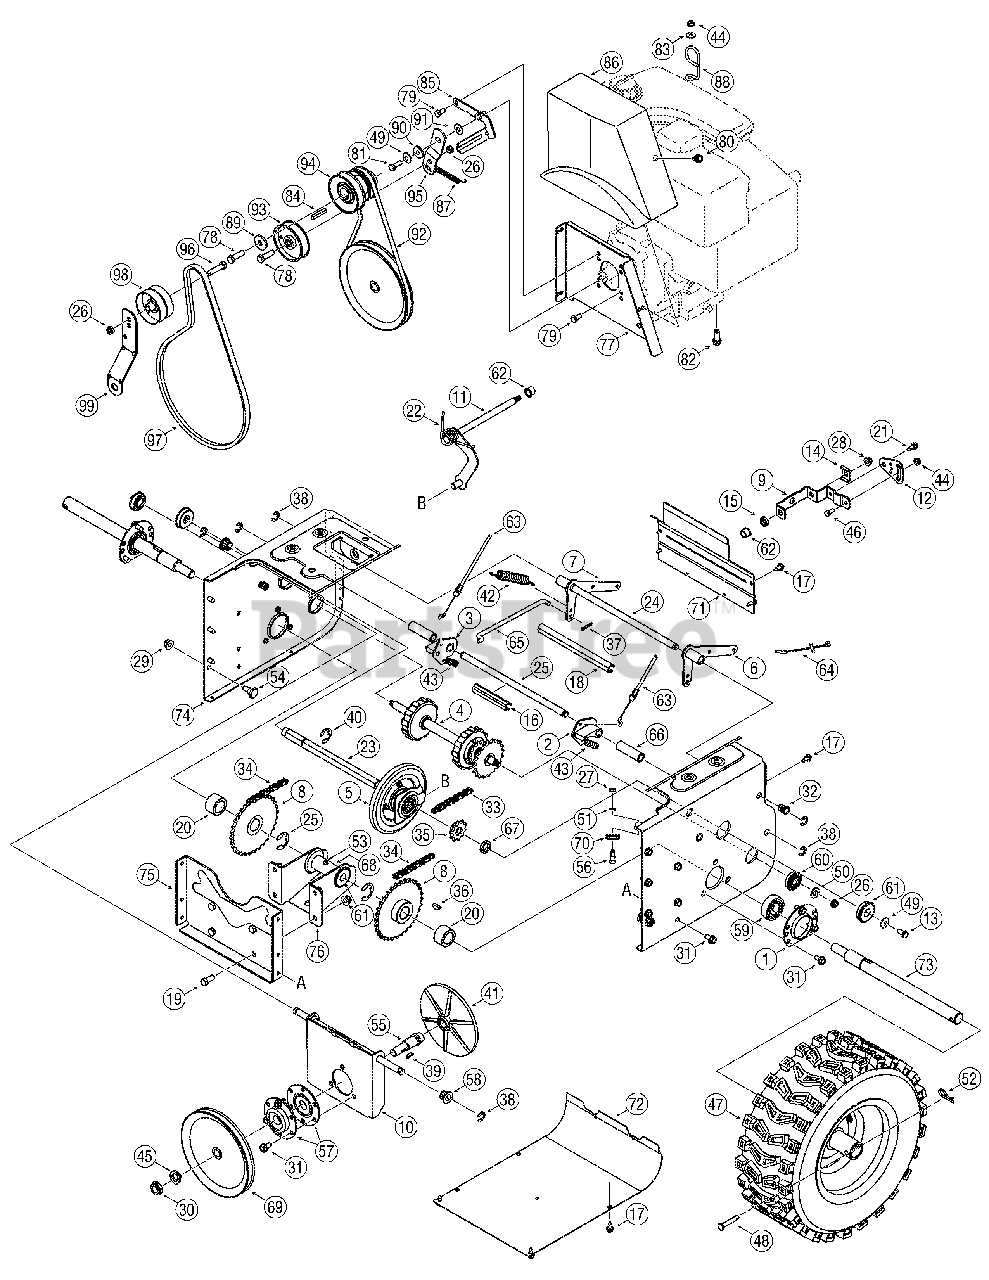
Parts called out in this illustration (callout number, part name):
1	Housing, Bearing
2	Dogg, Steering Drive, LH
3	Dogg, Steering Drive, RH
4	Shaft Assembly, Steering
5	Assembly, Friction Wheel
5	Wheel, Friction, Bonded
5	Screw, Hex Wash
11	Rod Assembly, Shift
13	Screw, Hex Cap Lock,
14	Bracket, Spacer, Shft.
15	Spacer, .515 ID x .750 OD
16	Spacer, .51 ID x 3.66 Lg.
17	Screw, Hex Wash.
18	Spacer, .51 ID x 7.895 Lg.
19	Screw, Hex Cap, 3/8-16
20	Spacer., 1.0 ID x 1.50 OD
21	Screw, Shoulder, .368 x .113
22	Spring, Torsion
23	Shaft, Hex Drive
24	Shaft, Actuator
25	Ring, Retainer
26	Nut, Hex Insert Jam Lock
27	Nut, Hex, 1/4-28 GR5
28	Nut, Hex Flnge Insert Lk
29	Nut, Hex Flnge Insert Lk
30	Nut, Hex Insert Jam Lk
31	TT Screw, 5/16-18 x .750
32	Nut, Insert 3/8-16
33	Chain, Endless, #41 x 36L
34	Chain, #420 x 40L
35	Sprocket, #41 x 10T
36	Key, Woodruff
37	Pin, Internal Cotter
38	E-Ring
39	Key, Hi-Pro, 3/16 x 5/8
40	Ring, Retaining
41	Plate, Drive
42	Spring, Extension
43	Spring, Extension
44	Flange, Lock Nut, 1/4-20
45	Washer, Lock, 5/8
46	Screw, 1/4-20 x .620
47	Wheel Assembly - LH
47	Valve
48	Pin, Clevis
49	Washer, Bell., .34 x .872 x .06
50	Washer, .406 x .875 x .059
51	Washer, Lock, 1/4
52	Pin, Internal Cotter
53	Fitting, Lube, 3/16 Drive
54	Screw, Shoulder, .498 x .34
55	Spindle, Drive Plate
56	Screw, Hex Shldr., 1/4-28
57	Assembly, Bearing/Housing
58	Bearing, Hex Flange
59	Bearing, Self Aligning
60	Bearing, Ball
61	Bearing, Ball
62	Bushing, Flange, .5 ID x .627 OD
63	Cable, Steering
64	Cable, Auger Idler
65	Rod, Drive Clutch
66	Spacer, .514 x .632 x 2.44
67	Spacer, .675 x 1.0 x .23
68	Spacer, .6725 x 1.125 x 2.48
69	Pulley, Drive
70	Roller, Cable
73	Axle, Wheel
78	Screw, 3/8-14 x 1.25 GR8
79	Screw, 5/16-24 x .625
80	Screw, Hx Wash Hd Tapp
81	Screw, Hx Cap 5/16-24
82	Screw, 3/8-16 x 1.00
83	Washer, Flat, .28 x .74 x .063
84	Key, Square, 1/4 x 1.5
87	Spring, Extension
88	Guide, Chute Cable
89	Washer, Flat, .406 x 1.25
90	Spacer, Shoulder
91	Washer, Flat, .349 x .879
91	Spacer, .33 ID x 1.01 OD x .36
92	V-Belt, 3V x 35.5
92	V Belt 3/8 X 34.4
93	Pulley, Flat Idler, 3.0 OD
94	Pulley, Dbl, 3.25 OD
95	Bracket, Idler, Drive
96	Screw, 3/8-24 x 1.50
97	V Belt,1/2 x 44
97	V Belt 1/2 x 42
98	Idler, Flat, 2.75 OD
99	Bracket, Idler, Auger
